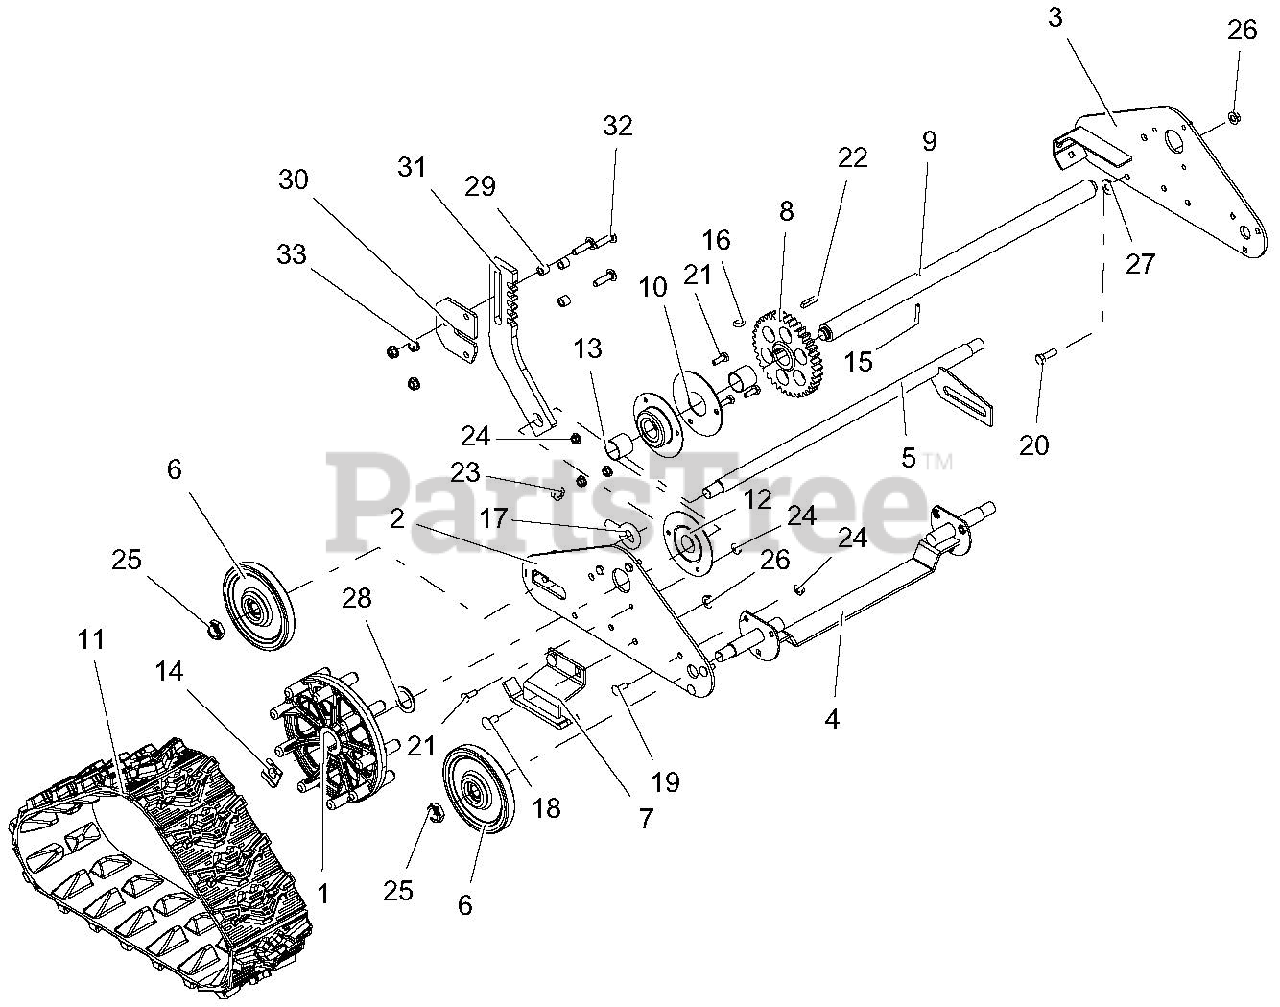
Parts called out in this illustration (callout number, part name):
1	WHEEL, MACHINED DRIVE
2	SIDE PLATE, RH COMPACT BLACK
3	SIDE PLATE, LH-COMPACT TRACK B
4	AXLE, FRONT-COMPACT TRACK
5	AXLE, REAR - DELUXE TRACK
6	WHEEL, BOGIE - SINGLE BEARING
7	RUNNER, GUIDE-CMPT TRACK BLACK
8	GEAR, SPUR
9	AXLE, TRACK-DELUXE
10	PLATE, BEARING SPACER
11	TRACK, RUBBER COMPACT
12	BRG-FLG 1.003/1.000 3 BOLT
13	BSHG-SLV, 1.012X1.125X1.00
14	CLIP, SNAP .625 DIA
15	PIN-ROLL .188X1.25
16	KEY-WDRF .25X.750X.313 SAE91
17	BLT-EYE .375-16X.880 YWZC
18	@BLT-RDHDSQNK .31-18X.75 G5YZ
19	@BLT-RDHDSQNK .25-20X.75 G5YZ
20	@BLT-HEX .31-18X1.00 GR5 YWZC
21	@BLT-HEX .25-20X.75 GR5 YWZC
22	KEY-RECT .25X.188X1.00
23	NUT-LK-CTR-FLG .38-16 YWZC
24	@NUT-LK-CTR-FLG .25-20 YWZC
25	@NUT-LK-NYL .625-18 YWZC
26	@NUT-LK-TOP-FLG .31-18 YWZC
27	BSHG-FLG .325X.499X.3X.875
28	WSHR-FL-STL 1.010X1.505X.062YZ
29	SPACER .50 X .32 X .42
30	PLATE, HEIGHT ADJUSTER
31	STOP, HEIGHT ADJUSTER-CPT BLAC
32	@BLT-RHDSHSQNK.31-18X1.25 G5YZ
33	@NUT-LK-TOP-FLG .31-18 YWZC
